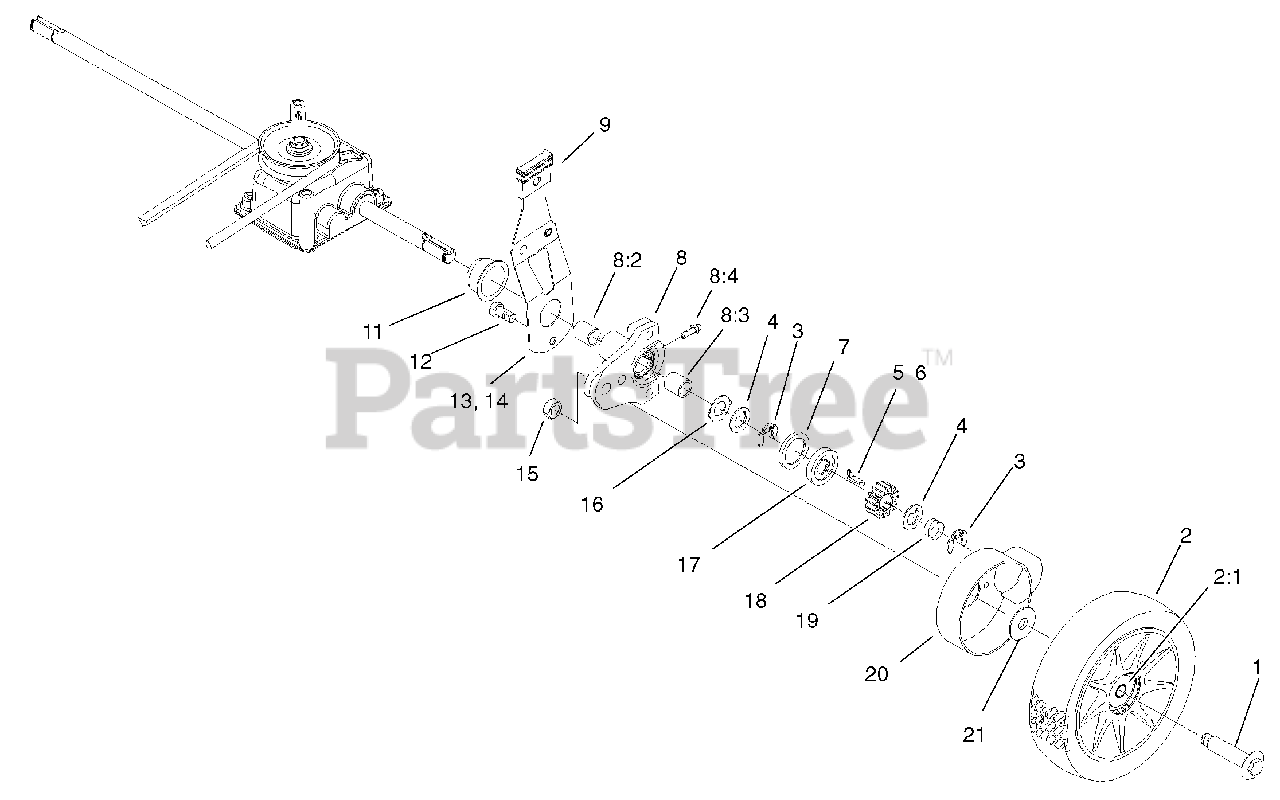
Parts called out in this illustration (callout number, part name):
1	BOLT-SHOULDER
2	WHEEL & TIRE ASM
3	RING-KLIP
4	WASHER-THRUST, KEYED
5	KEY-ROCKING, LH
6	KEY-ROCKING, RH
7	RING-FRICTION
8	REAR HEIGHT ADJUSTMENT ARM ASM
8:4	FITTING-ZERK
9	KNOB-LEVER, HEIGHT ADJUSTMENT
11	RING - ISOLATOR
13	LH REAR SPRING ARM ASM
14	RH REAR SPRING ARM ASM
16	WASHER-ARM, PIVOT
17	WASHER-CLUTCH
18	GEAR-PINION
19	SPRING-COMPRESSION
20	COVER-WHEEL
21	WASHER-STEPPED
